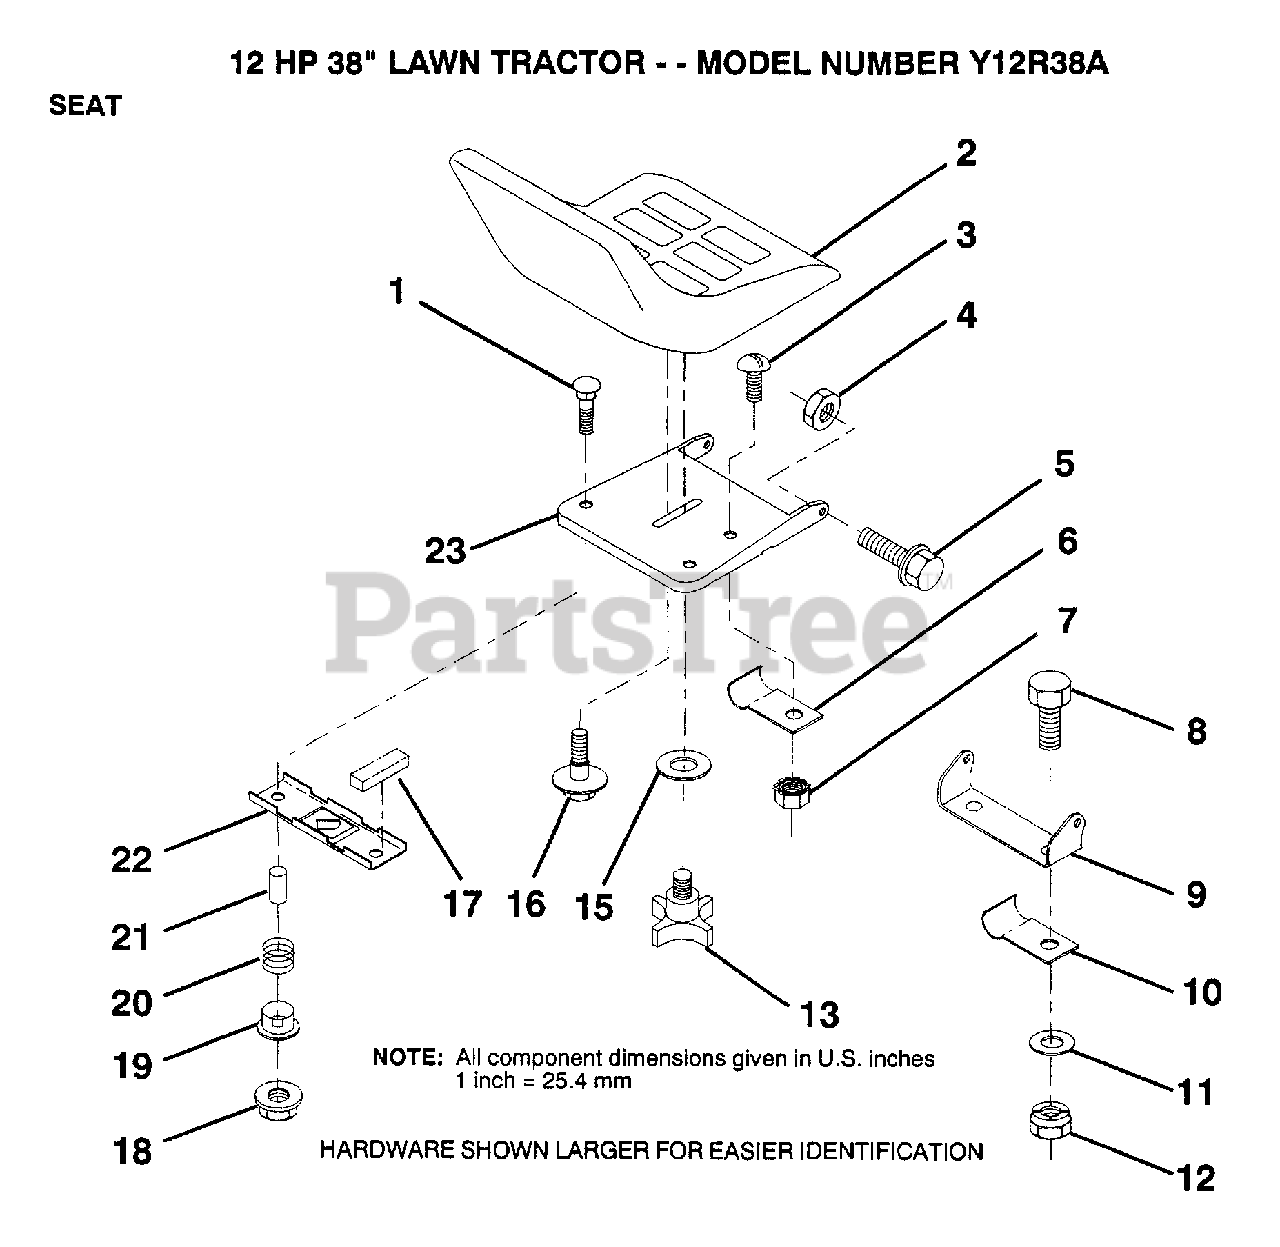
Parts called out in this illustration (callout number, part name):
7	"NUT,KEPS"
10	"CLIP,INSULATOR"
11	WASHER
13	"KNOB 1/2"" YT"
15	WASHER
16	"BOLT,SHOULDER"
17	STRIP FORM
19	BUSHING
20	SPRING
21	SPACER SPLIT
22	BRKT SWITCH
